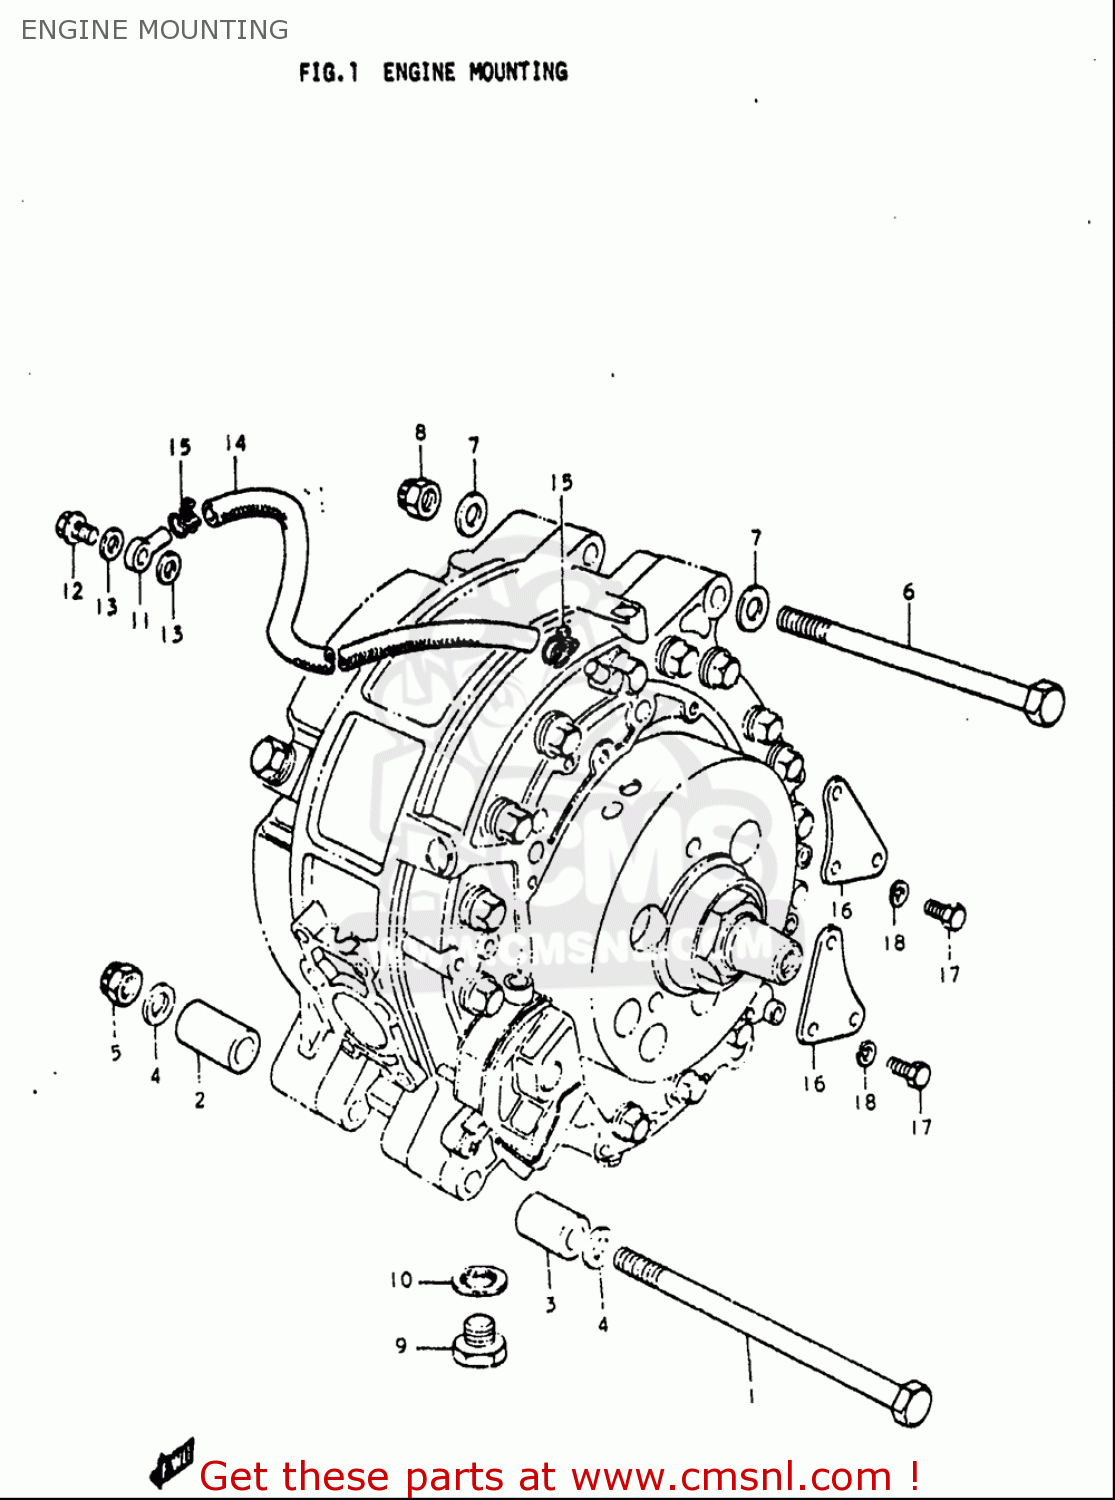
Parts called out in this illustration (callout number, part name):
4	WASHER
5	NUT
7	WASHER
8	NUT
9	PLUG(MAGNETO)
10	GASKET(14X19.2X2) (NAS)
11	UNION
12	UNION BOLT
13	GASKET(6.2X11X1).2 (NAS)
14	HOSE(5.5X9.5X400)
15	CLAMP
17	BOLT
18	WASHER,LOCK
